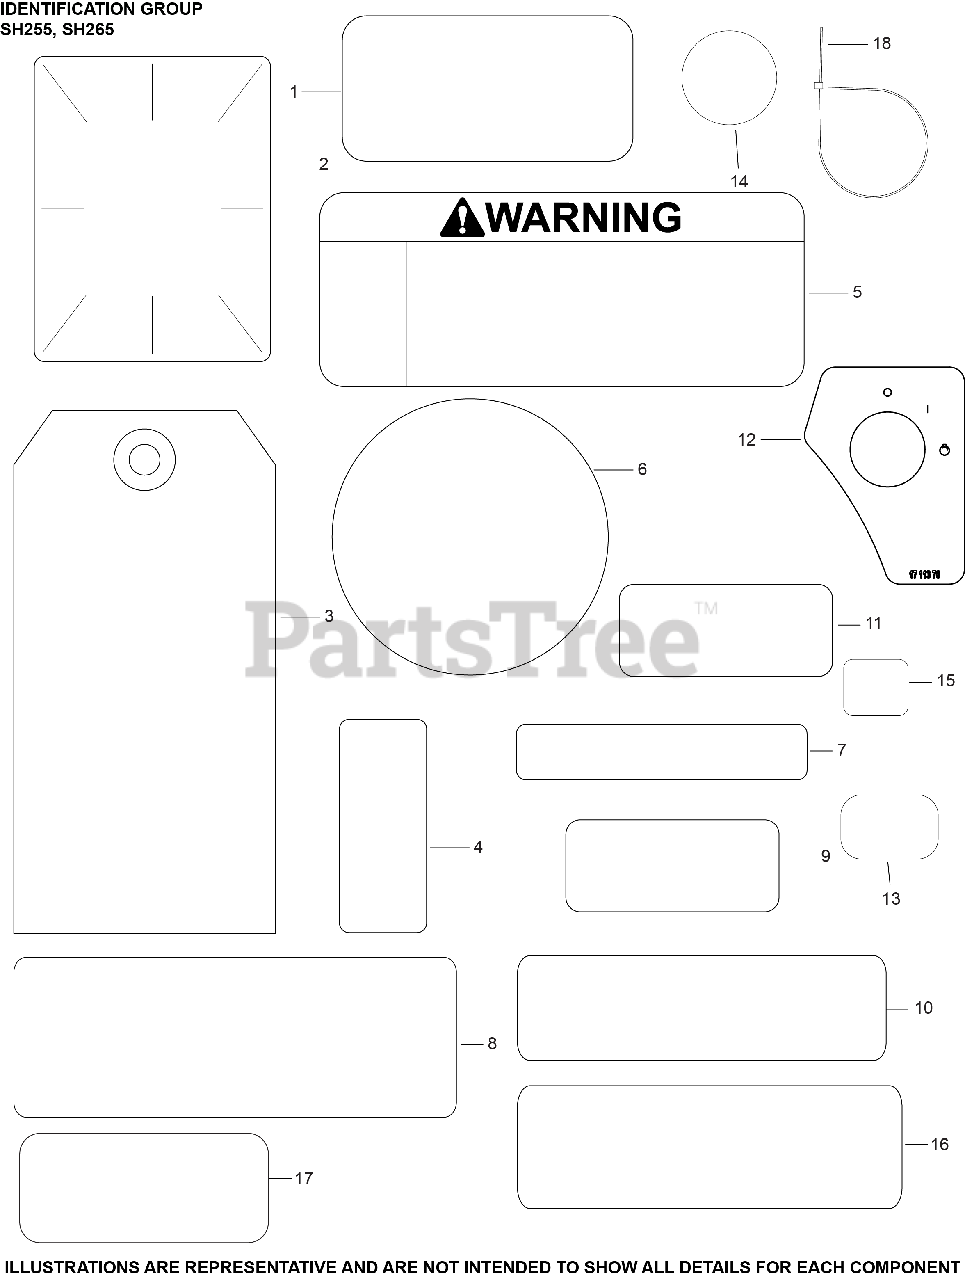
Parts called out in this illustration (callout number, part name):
1	LABEL, MAINTENANCE (CKY)
2	LABEL, CLEAR LAMINATION
3	TAG, HANG
6	LABEL, RECOIL 75MM
8	LABEL, HORSEPOWER
11	LABEL, CANADIAN COMPLIANCE
15	LABEL, LPAC CHOKE
